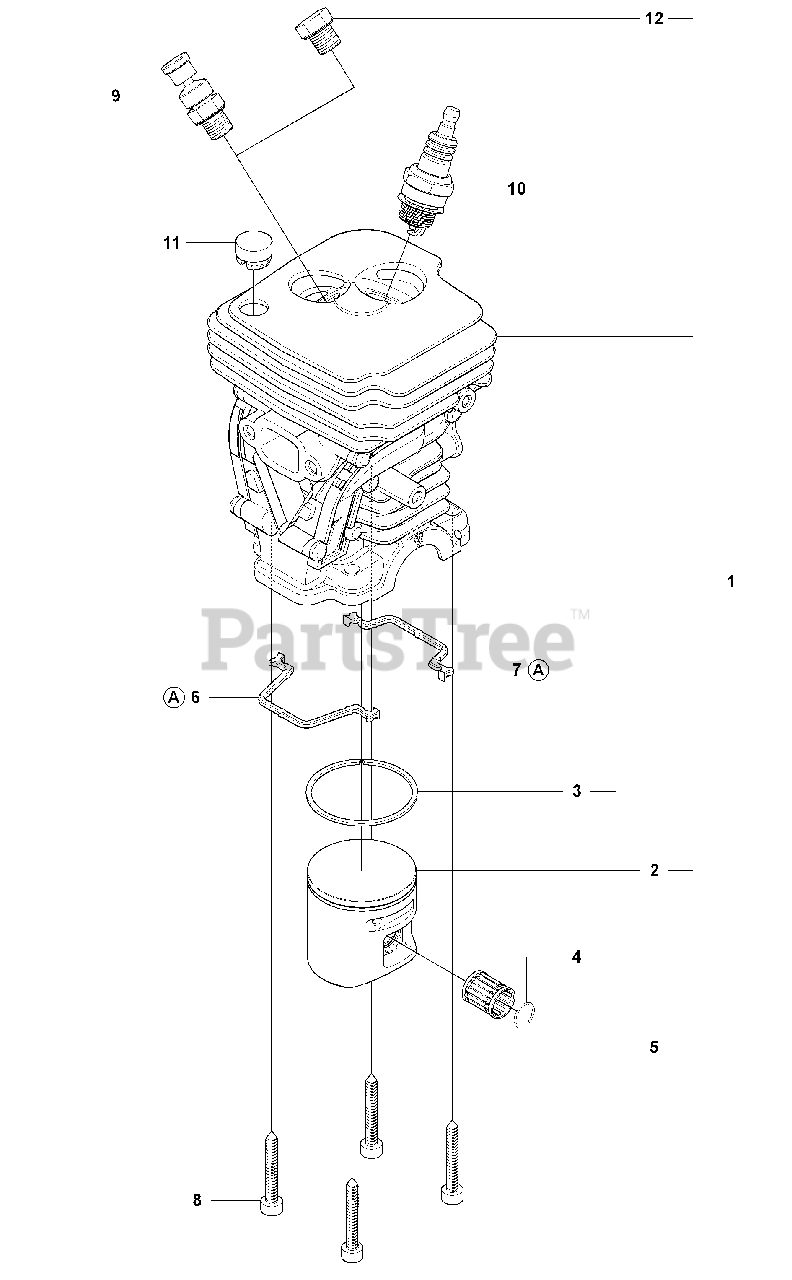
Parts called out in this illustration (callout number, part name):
2	PISTON ASSY
3	PISTON RING
5	SUPPORT BUSHING
9	DECOMPRESSION VALVE
10	BPMR7A NGK SPARK PLUG
12	CYLINDER PLUG
